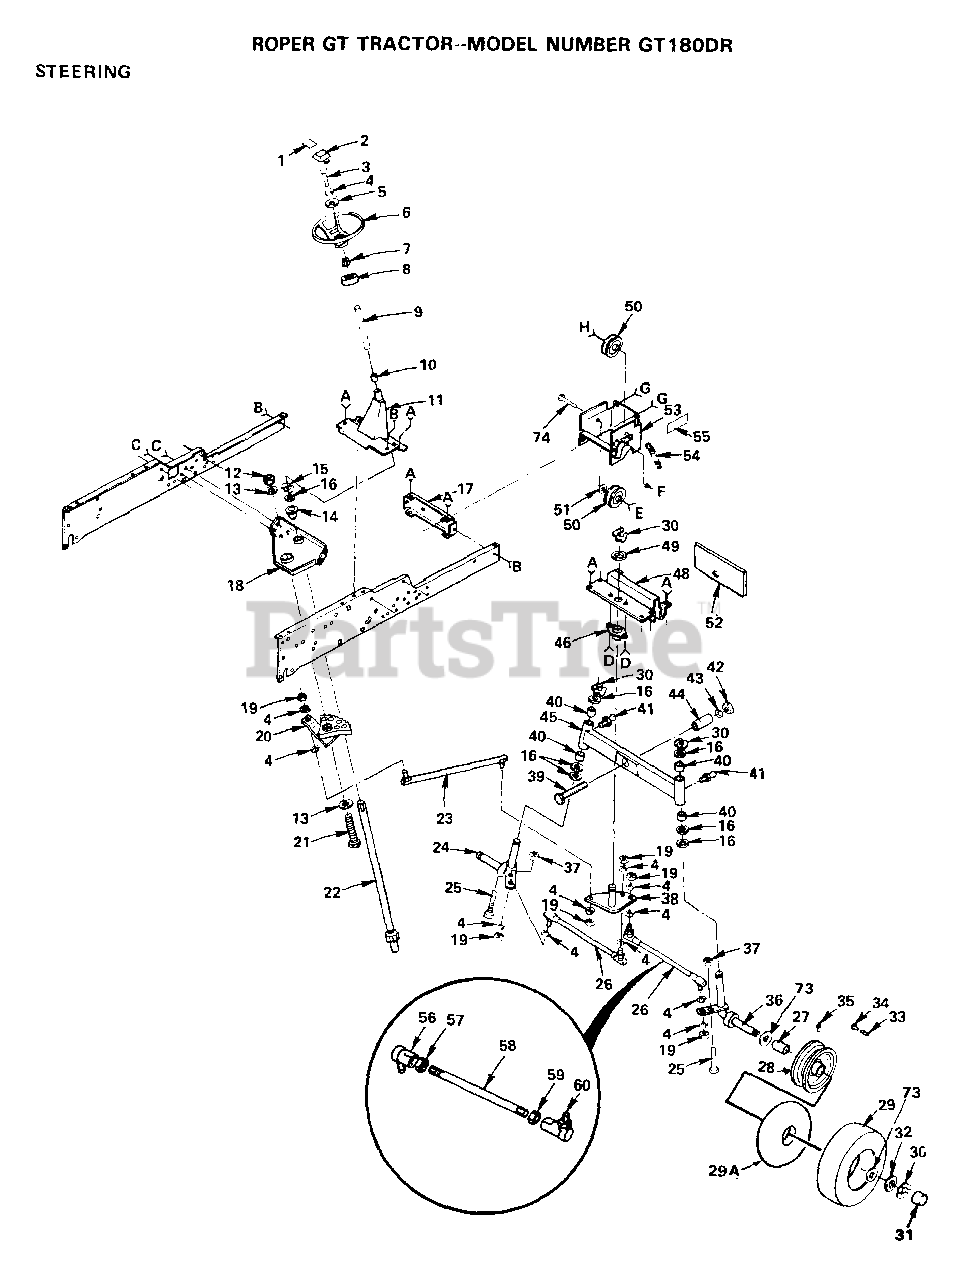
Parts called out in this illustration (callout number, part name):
1	DECAL - STEERING WHEEL
2	INSERT-WHEEL LT
3	BOLT
4	LOCKWASHER
5	WASHER T
7	ADAPTER LT
9	TUBE
10	"T, BEARING"
11	SUPPORT ASSY T
12	NUT LTV
13	WASHER GT
14	"FLANGE GT, BEAR."
15	KLIP RING
16	WASHER .T
17	FRAME BRACKET GT
21	BOLT
22	SHAFT STEERING GT
24	SPINDLE ASSY T
25	BOLT, HEX 3/8 - 16 X 2
27	"FLANGE, BEARING"
29A	TUBE.16X6.5/7.5-8
30	RING
31	HUB CAP
33	VALVE CAP
34	VALVE STEM LT
35	FITTING LT
36	SPINDLE RH T
37	NUT
38	"T, BELLCRANK"
39	BOLT
40	BRNG. T
41	ZERK M
42	NUT X
43	WASHER
45	AXLE ASSEMBLY
48	AXLE BRACKET T
49	WASHER
50	IDLER-INSIDE T
51	WASHER T
54	SPRING
57	NUT
59	NUT
